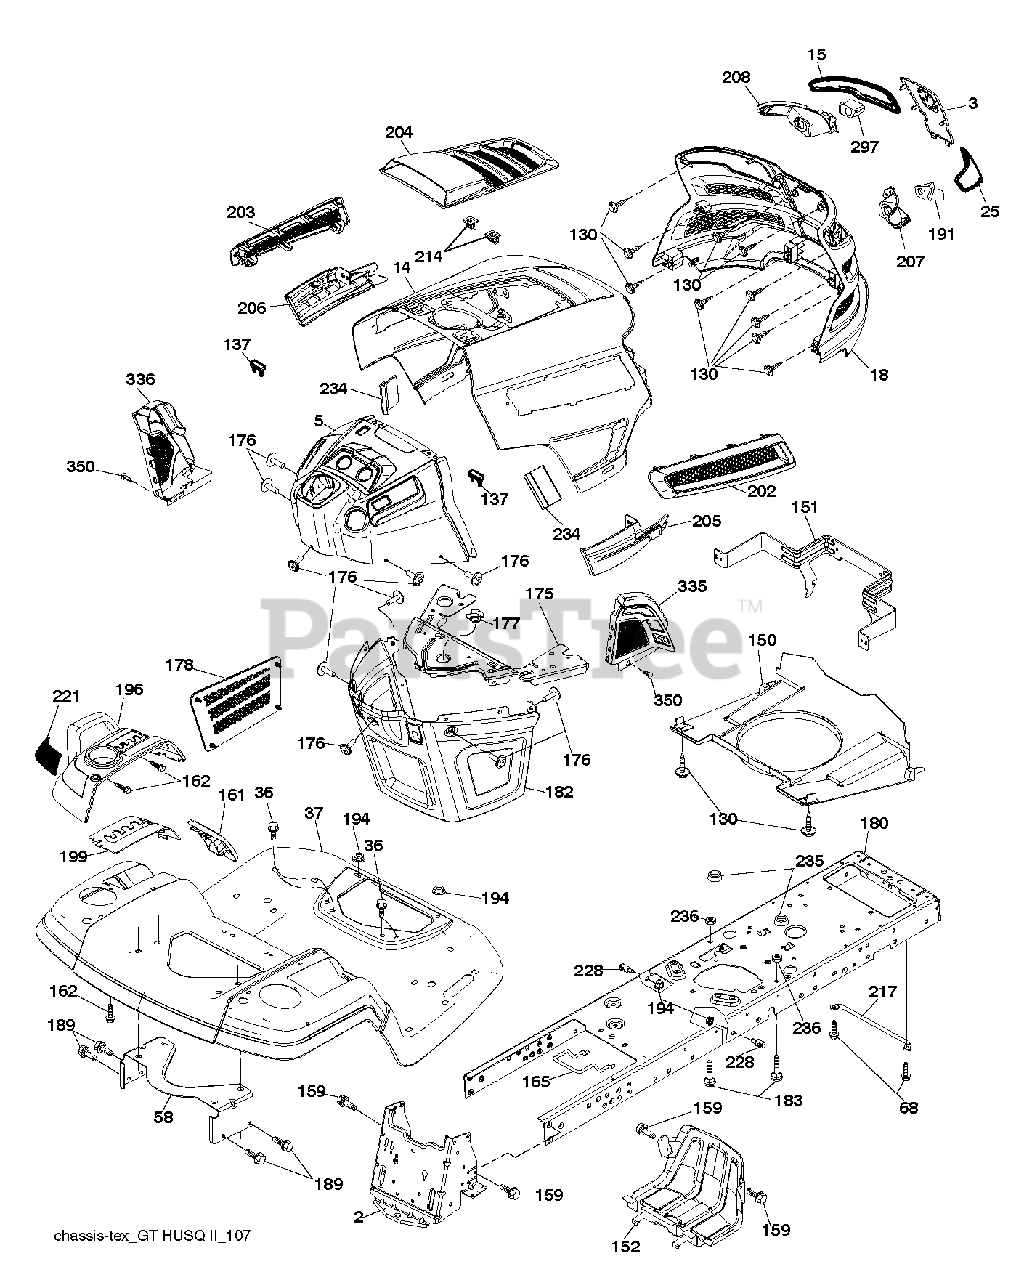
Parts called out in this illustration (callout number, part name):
2	DRAWBAR.STGT
3	APPLIQUE.SUBASM.GT.HUSQ.II
5	DASH.UPP.GT2.DR.PTO.DCKLFT.MC
14	HOOD.ASM.HUSQVARNA.GT.TEX.422
15	LENS.HEADLIGHT.LH.GTII.2011
18	GRILLE.SUBSTRATE.2011.
25	LENS.HEADLIGHT.RH.GTII.2011
36	SCREW 5/16"
37	FENDER.PNT.TX.GT.CH/FW/DL.HUSQ
58	BRKT.SUPPORT.FNDR/TANK
68	SCREW LT
130	SCREW.#10 X 0.750.BOS
137	BUMPER DASH
150	AIR.DUCT.GTV.BLACK
151	BRACKET.PIVOT.HOOD.GT.HUSQ.II
152	SHIELD.BROWNING.PNT.GT.V2
159	SCREW, 3/8-16X3/4
161	CONSOLE.WINDOW.FUEL.HUSQ.GT
162	SCREW.HI-LO.CONSOLE
165	SUPPORT.TANK.REAR.B/TE
175	PLATE.CROSSMEMBER.HUSQ
176	SCREW.#10-24X5/8.RN.QU
177	BUSHING, STEERING
178	CARGO.ASM.NET.TXGT.W/C
180	CHASSIS.TEX.BOLTED
182	DASH.LOWER.COMMON.12V.ADAPTOR
183	BOLT.5/16-18X1-1/4 FULL THD
189	SCREW
191	INSERT.REFLECTIVE.RH.HUSQ.GTII
194	NUT LOCK HEX FLANGE 5/16-18
196	CONSOLE.ASM.DECKLIFT.HUSQGT.DL
199	PLATE.DECK.LIFT.HUSQVARNA.GT
202	VENT.SIDE.RH.GT.HUSQ.II.
203	VENT.SIDE.LH.GT.HUSQ.II.498
204	VENT.TOP.HUSQ.GT2
205	SIDE.TRIM.RH.GT.HUSQ.II
206	SIDE.TRIM.LH.GT.HUSQ.II.GRAY
207	BEZEL LIGHT.RH.GT.II.MYLAR
208	BEZEL LIGHT.LH.GT.II.MYLAR
214	CLIP.RETAINER.TINNER.
217	ROD.PIVOT.HOOD
221	REFLECTOR.LH.TEX GT HU
228	STUD.FASTNER.W/ANTI-ROTATE
234	BUMPER.HOOD.TEX.HUSQVARNA
235	SPACER FENDER
236	NUT.CENTERLOCK.5/16-
297	INSERT.REFLECTIVE.LH.HUSQ.GTII
335	COVER.LOWER.DASH.RH.BLACK
336	COVER-LH.LOWER.DASH.GT2.BLACK
350	KIT GUARD BRUSH
